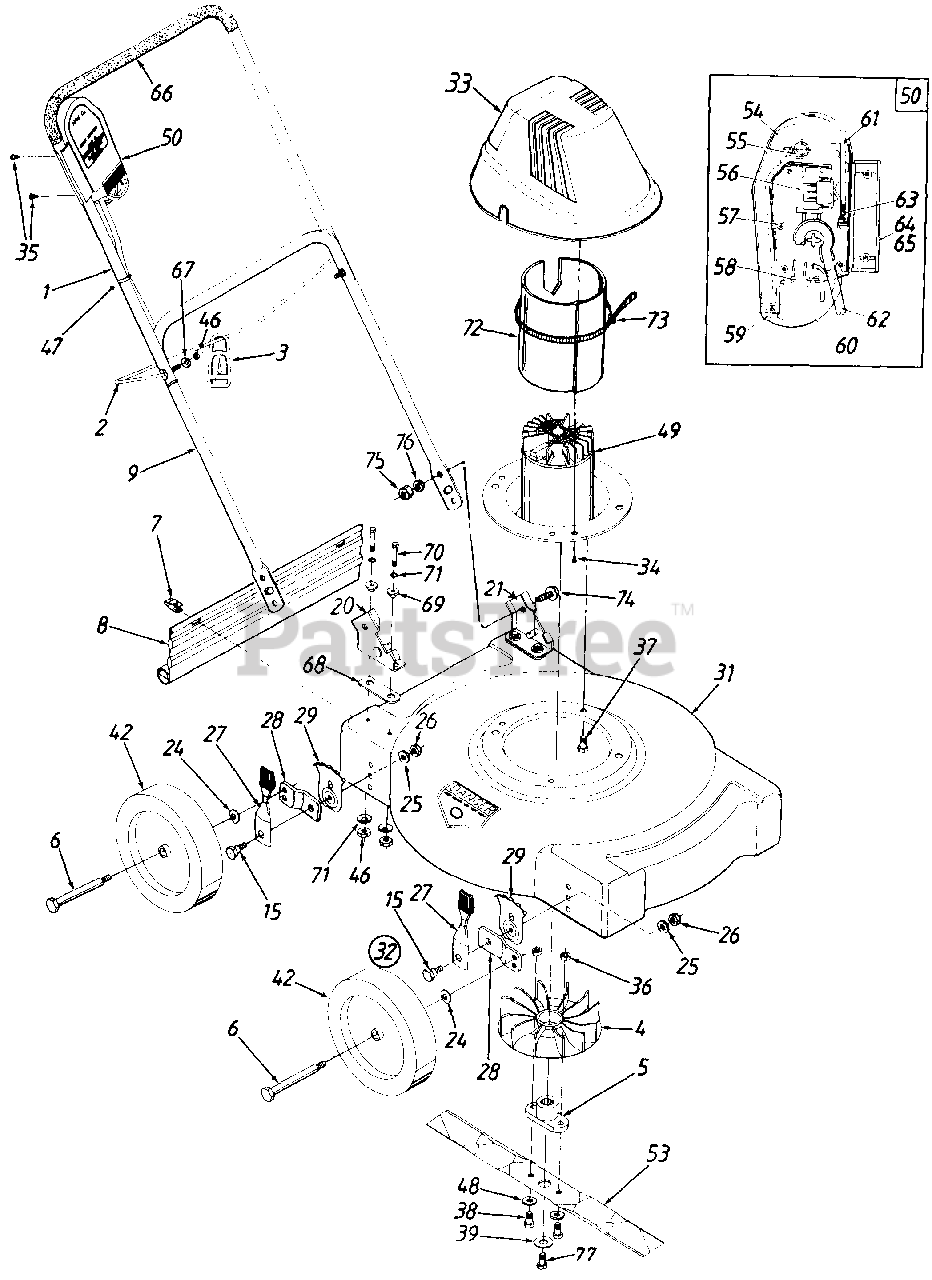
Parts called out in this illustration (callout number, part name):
1	Upper Handle
2	Cord Control Rod
3	Strain Relief - Cord
5	Blade Adapter
6	Axle Bolt
7	Hinge Clip
8	Rear Flap
9	Lower Handle
15	Shld Bolt 5" Dia x .434"
20	Handle Brkt Ass'y.- R.H
21	Handle Brkt. Ass'y.- L H
24	Bell-Wash .38" I.D. x .88" O.D.
25	Bell-Wash .39" I.D. x 1.38" O.D.
26	Hex Nut 3/8-16 Thd
27	Spring Lever Ass'y w/Knob
29	Height Adj Plate
31	20" Deck Ass'y.
32	Height Adj Ass'y Comp - R.F. & L.R.
33	Motor Cover
34	Scr #10-16 x .75" Lg.
35	Self-Tap Scr #7 x 1" Lg.
36	Hex Nut 3/8-24 Thd.
37	Hex L-Wash. TT-Tap Scr 3/8-16 x .75" Lg.
38	Hex Bolt 3/8-24 x 1.25" Lg.
39	Bell-Wash 396" I.D. x 1.14" O.D.
42	Wheel Ass'y Comp
46	Hex Top L-Nut 1/4-20 Thd.
47	Cable Tie
48	Bell-Wash. 3/8" I.D.
49	Motor, Cord & Switch Ass'y.
50	Cord & Switch Ass'y. Comp (See Breakdown)
53	20" Mulching Blade
54	Handle - Switch Actuator
55	Spring - Switch Handle
56	Switch
57	Screw #6-32 x .5" Lg
58	Plug Ass'y
59	Retainer Plug Spring
60	Retainer Plug
61	Latch
62	Cord Ass'y.
63	Spring Latch
64	Housing - Upper Half
66	Foam Grip
67	Curved Wash 5/16" I.D.
68	Insulator Strip
69	Insulator Shield
70	Hex Bolt 1/4-20 x 1" Lg.
71	Fl-Wash. 26" I.D x .72" O.D.
72	Insulator
73	Cable Tie
74	Phillips Hd. Scr 5/16 x .75" Lg.
75	Hex Nut 5/16-18 Thd
76	L-Wash 5/16" I.D.
77	Hex Bolt 3/8-24 x 2.5" Lg.
